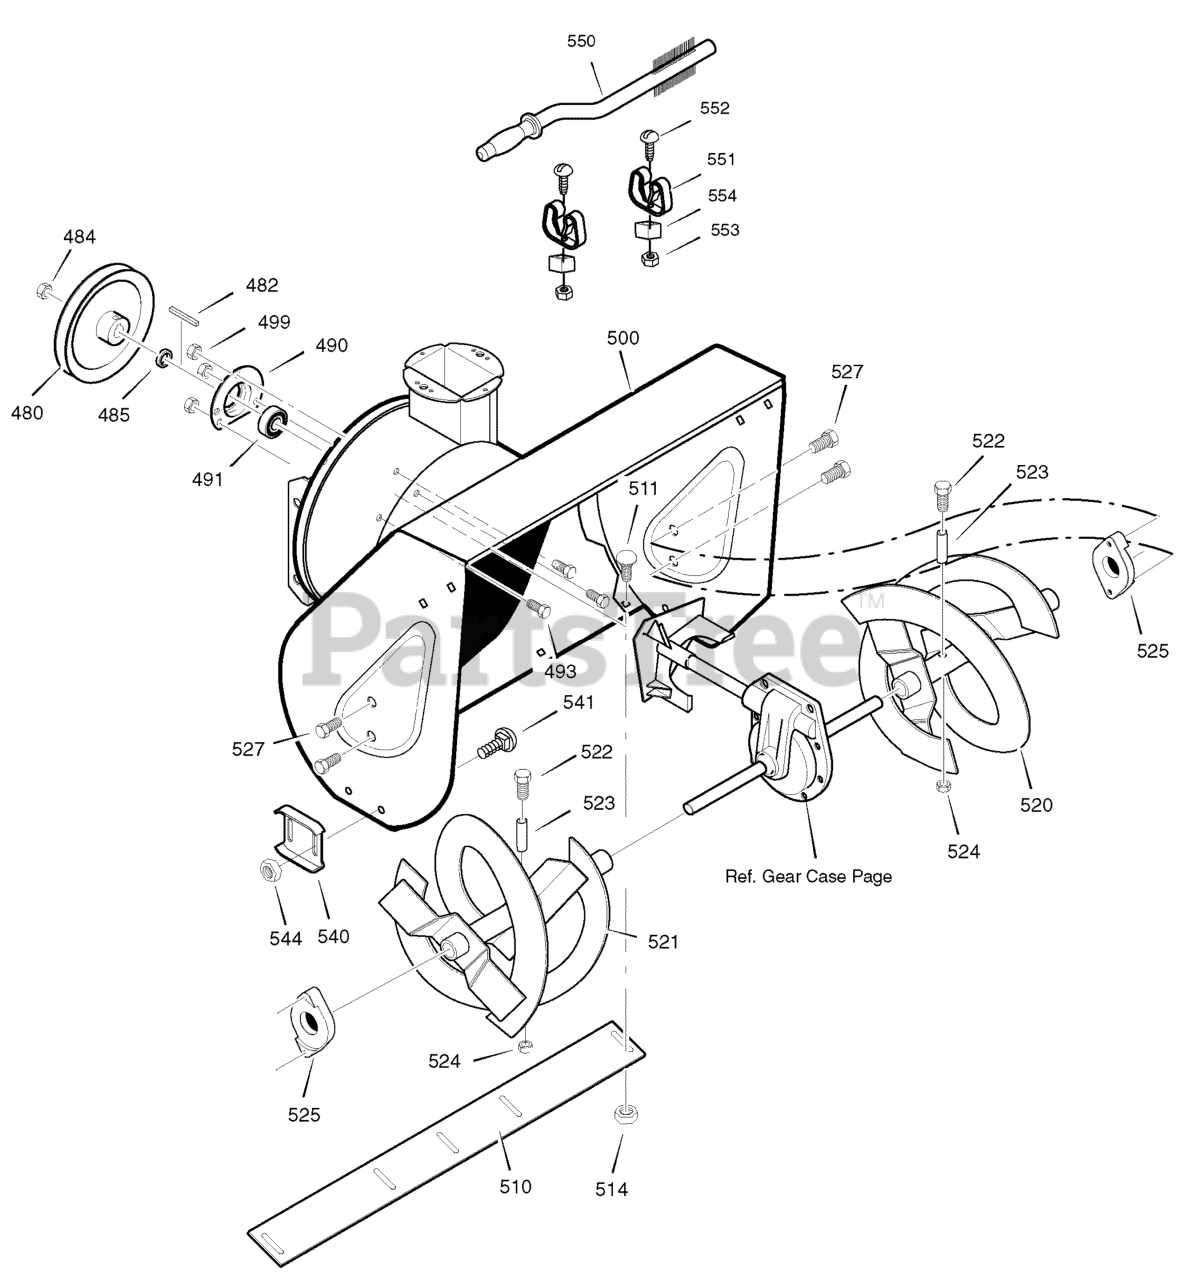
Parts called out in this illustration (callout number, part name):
480	PULLEY, 4L 8.40 OD
482	KEY, SQUARE 3/16 X 3/4
484	NUT, 1/2-20
485	SPACER, FRICTION PULLEY
490	RETAINER, BALL BRNG
491	BEARING, BALL
493	BOLT, HEX 5/16-18X .50
499	NUT, 5/16-18 HEXWDFLLK
500	HOUSING, ASSY
510	BLADE, SCRAPER
511	BOLT, 5/16-18X.75
514	NUT, 5/16-18
520	AUGER, ASSY, LH
521	AUGER, ASSY, RH
522	SCREW, 1/4-20 X 1.75
523	SPACER, SLEEVE
524	NUT, 1/4-20
525	BEARING, FLANGE
527	SCREW, 5/16-18 x 0.75
540	SKID, HEIGHT ADJUST
541	BOLT, 5/16-18 X .75
544	NUT, 5/16-18
550	BRUSH, CLEANOUT
551	CLIP, RETAINER
